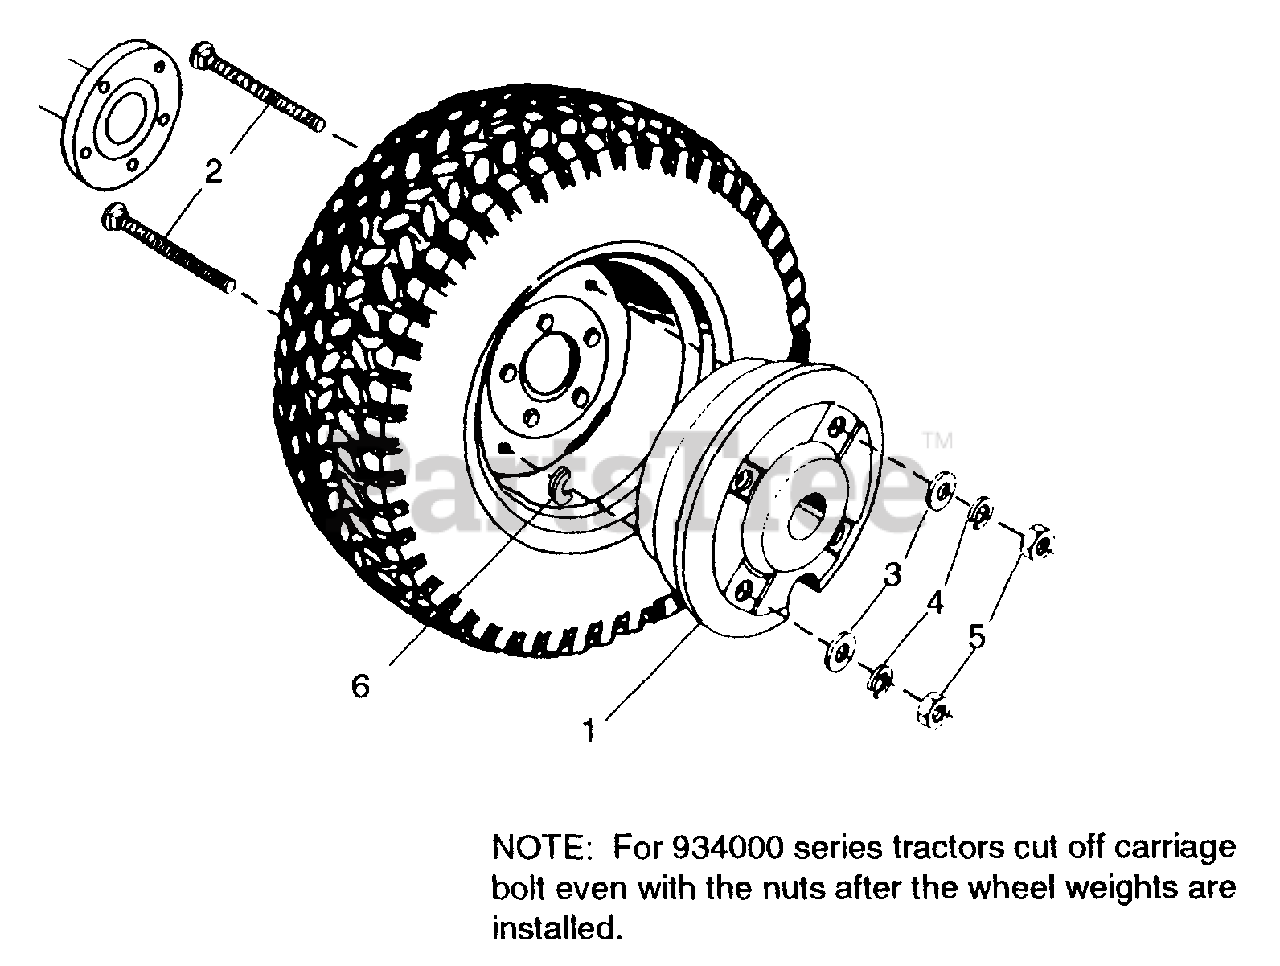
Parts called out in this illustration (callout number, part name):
1	WHEEL WEIGHT 75 LB.
2	BLT-RDHDSQNK .50-13X9.00 YWZC
3	WSHR-FL-STL .531X1.062X.095 PL
4	WSHR-LK .500X.151 HVY PL
5	NUT .50-13 PL
6	GROMMET .438ID X .688 OD
